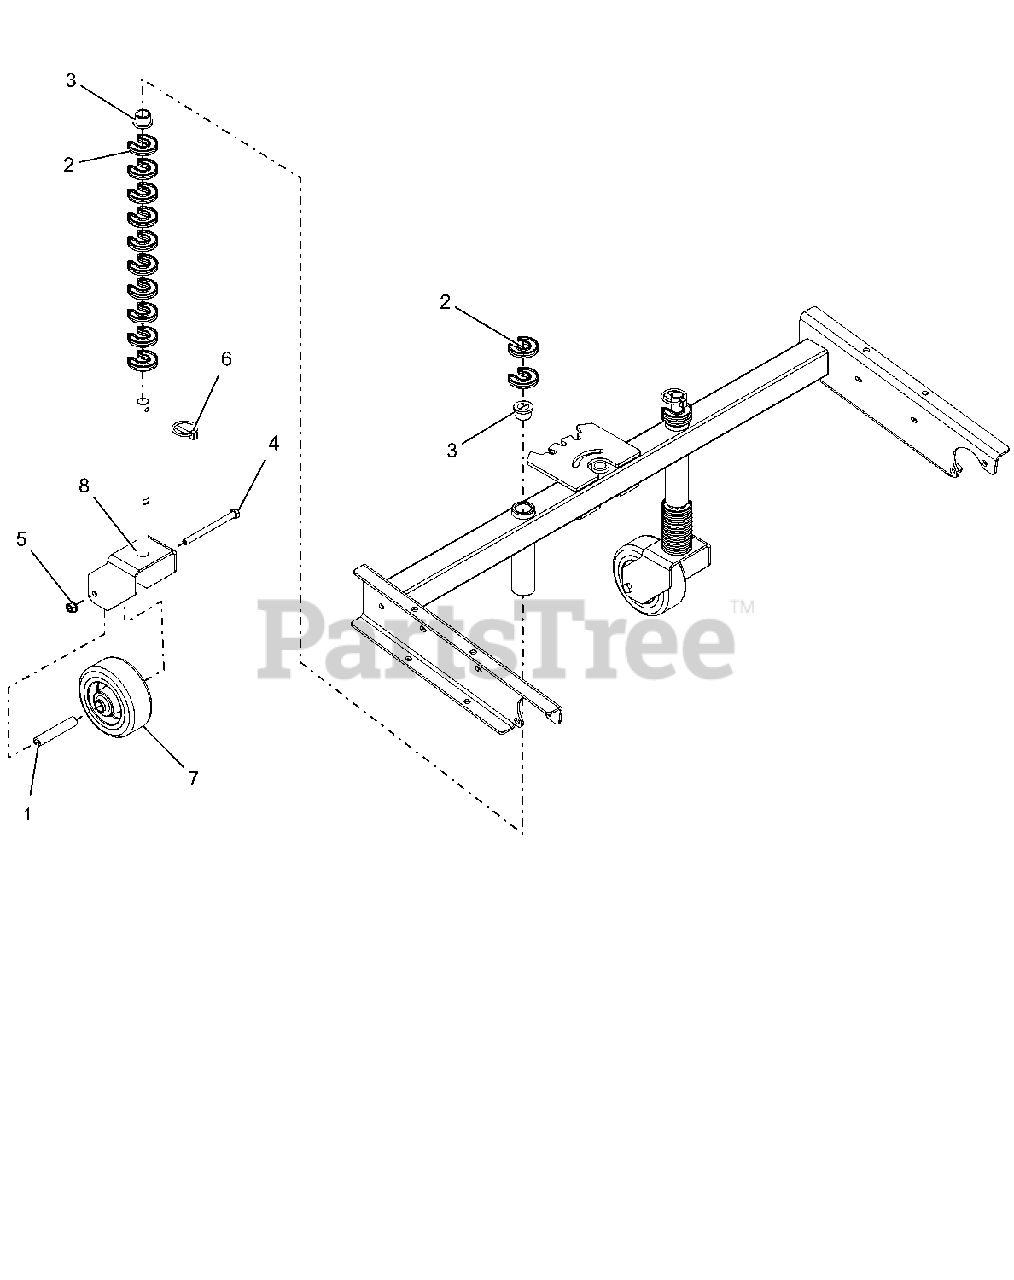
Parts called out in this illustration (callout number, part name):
1	SPACER, CASTER WHEEL
2	CLIP-HOC FIXED
3	BUSHING, FLANGE .75X.75X1.0
4	BLT-HEX .38-16X4.50 GR5 YWZC
5	NUT-LK-TOP-FLG .38-16 YWZC
6	PIN, 1/4X1-9/16 LYNCH
7	WHEEL, CASTER - 5"OD
8	FORK, CASTER
